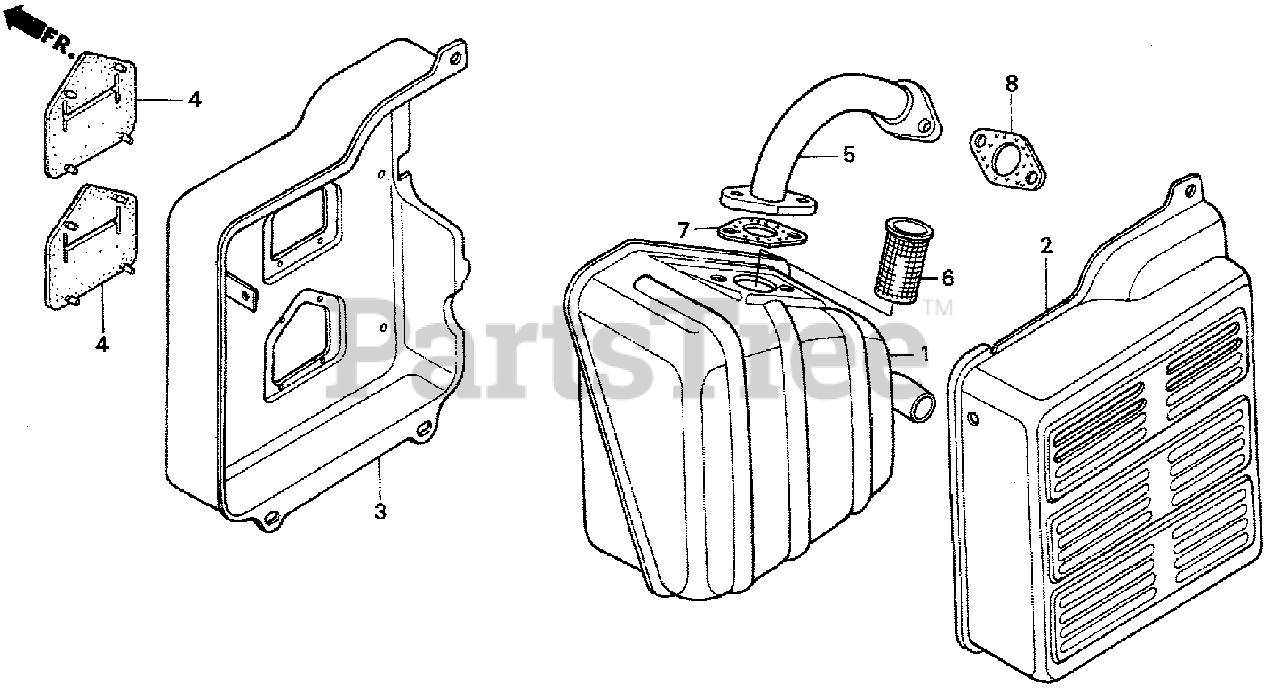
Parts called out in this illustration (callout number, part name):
1	MUFFLER
2	PROTECTOR, MUFFLER (OUTER)
3	PROTECTOR, MUFFLER (INNER) (DENYO)
4	SEAL, MUFFLER PROTECTOR
5	PIPE, EX. (DENYO)
6	ARRESTER, SPARK
7	GASKET, MUFFLER
8	GASKET, MUFFLER
